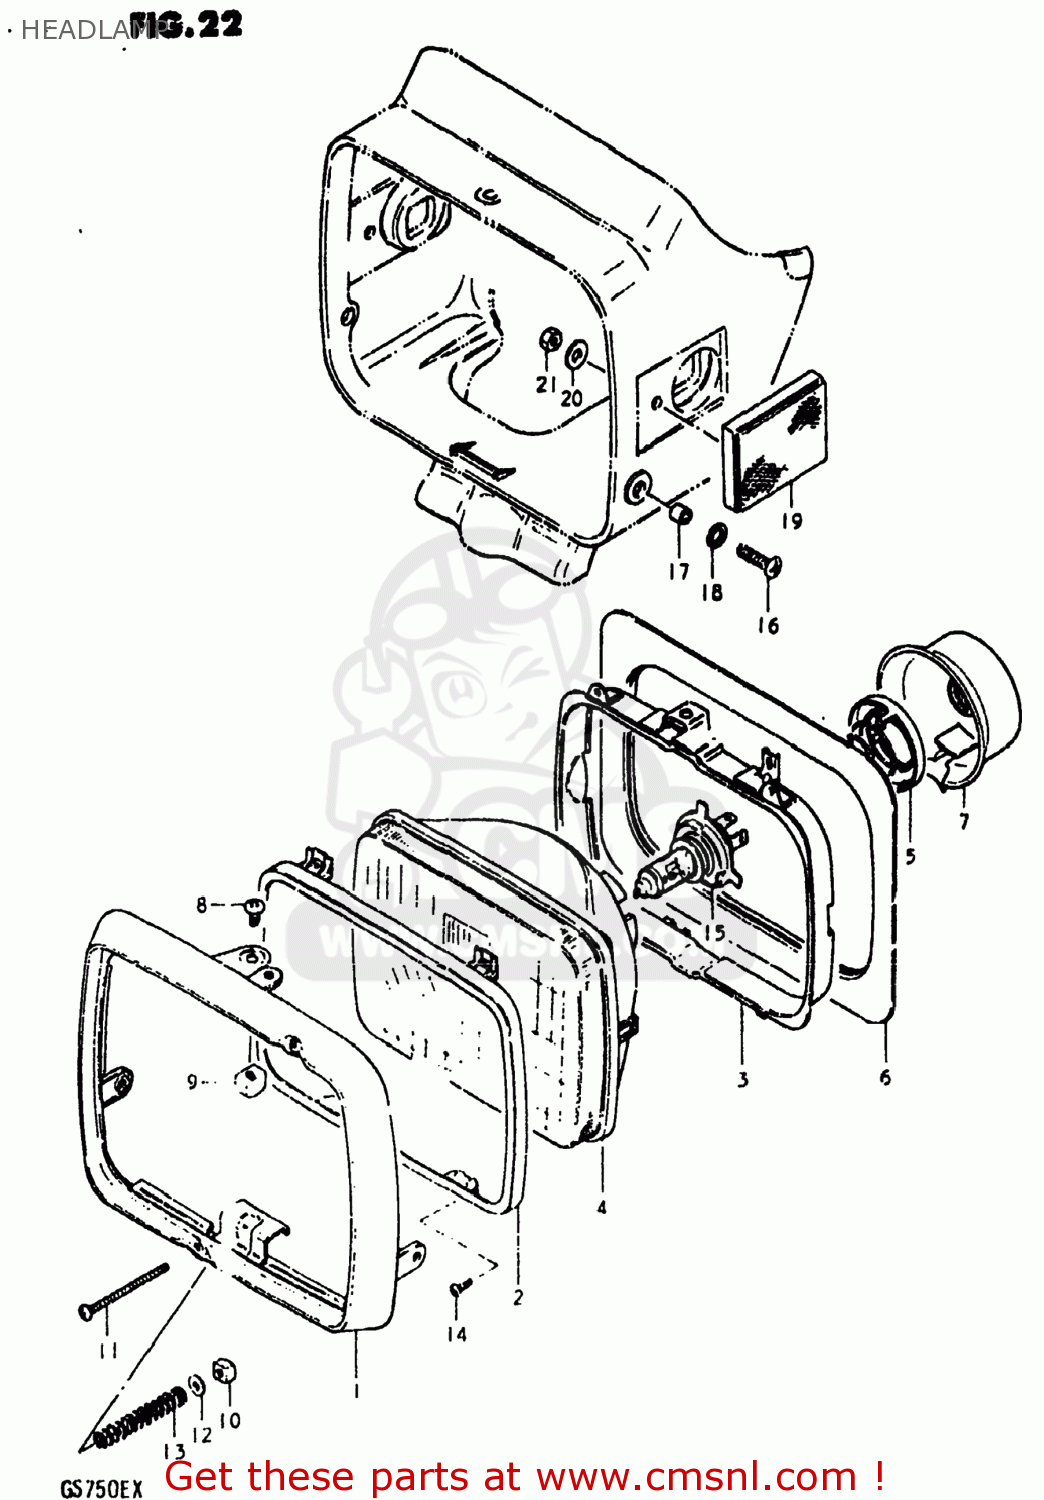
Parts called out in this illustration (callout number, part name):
1	RIM
2	RETAINER,HEADLAMP
3	RING,HEADLAMP UNIT
4	LAMP UNIT
5	HOLDER
6	SHADE
7	COVER,HEADLAMP SOCKET
8	SCREW
9	NUT,HEADLAMP ADJUSTER
10	NUT
11	SCREW,HEADLAMP ADJUST
12	WASHER
13	SPRING
14	SCREW
15	BULB(12V60/55W,H4)
16	SCREW
17	SPACER (5.2X8X7.5)
18	GASKET(8.2X12X0.8) (NAS)
19	REFLEX REFLECTOR,FR
20	WASHER(5.2X16X1)
21	NUT
